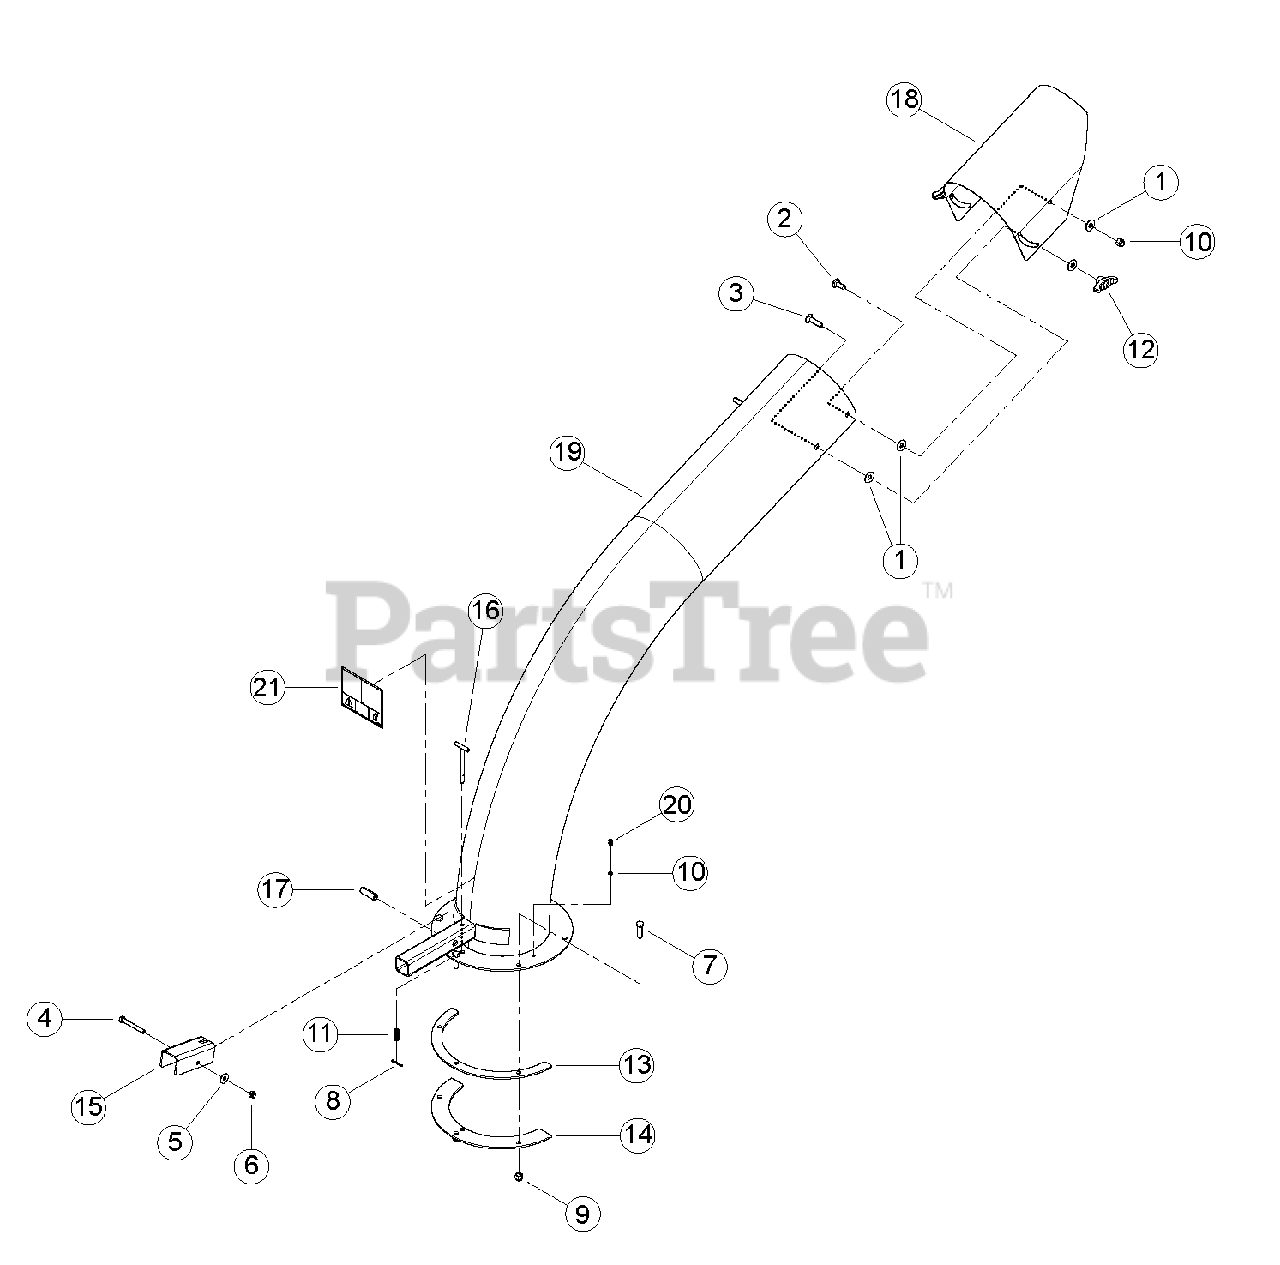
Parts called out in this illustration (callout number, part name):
1	WASHER, 3/8 FLAT ZP
2	BOLT, 3/8 X 1 CRG GR5 NC ZP
3	BOLT, 3/8 X 1-1/2 CRG GR5 NC ZP
4	BOLT, 5/16 X 2-1/2 HX CAP GR5 ZP
5	WASHER, 5/16 FLAT ZP
6	NUT, 5/16 NE NYLOCK ZP
7	BOLT, 3/8 X 1-1/4 HEX HD GR5 ZP
8	PIN, 1/8 X 1 ZP COTTER
9	NUT, 3/8 NE NYLOCK ZP
10	WASHER, .254 X .400 X .048 FLAT
11	SPRING, LOCK COMPRESSION
12	KNOB, 3/8-16 UNC FEMALE TEE
13	RING, DISCHARGE SPACER
14	RING, DISCHARGE CLAMP
15	LEVER, DISCHARGE LOCK
16	WELDMENT, DISCHARGE LOCK PIN
17	TUBE, DISCHARGE LOCK PIVOT
18	CAP, 8 IN. DISCHARGE CHUTE
19	ASSEMBLY, 8 INCH DISCHARGE SERVICE PART
20	FITTING, 1/4 SELF-TAP GREASE
21	DECAL, DISCHARGE DEBRIS & LOCK
